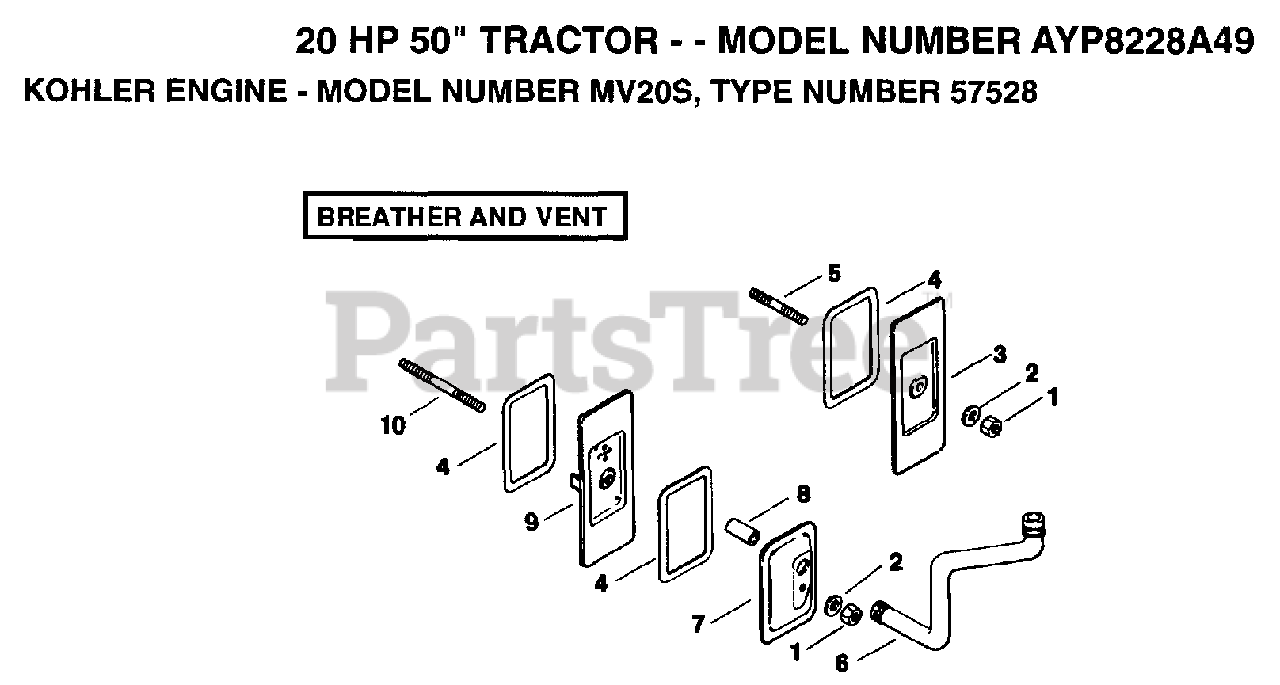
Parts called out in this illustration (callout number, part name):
1	NUT
2	WASHER
5	STUD
8	SEAL BREATHER
9	BREATHER ASSY
10	STUD
